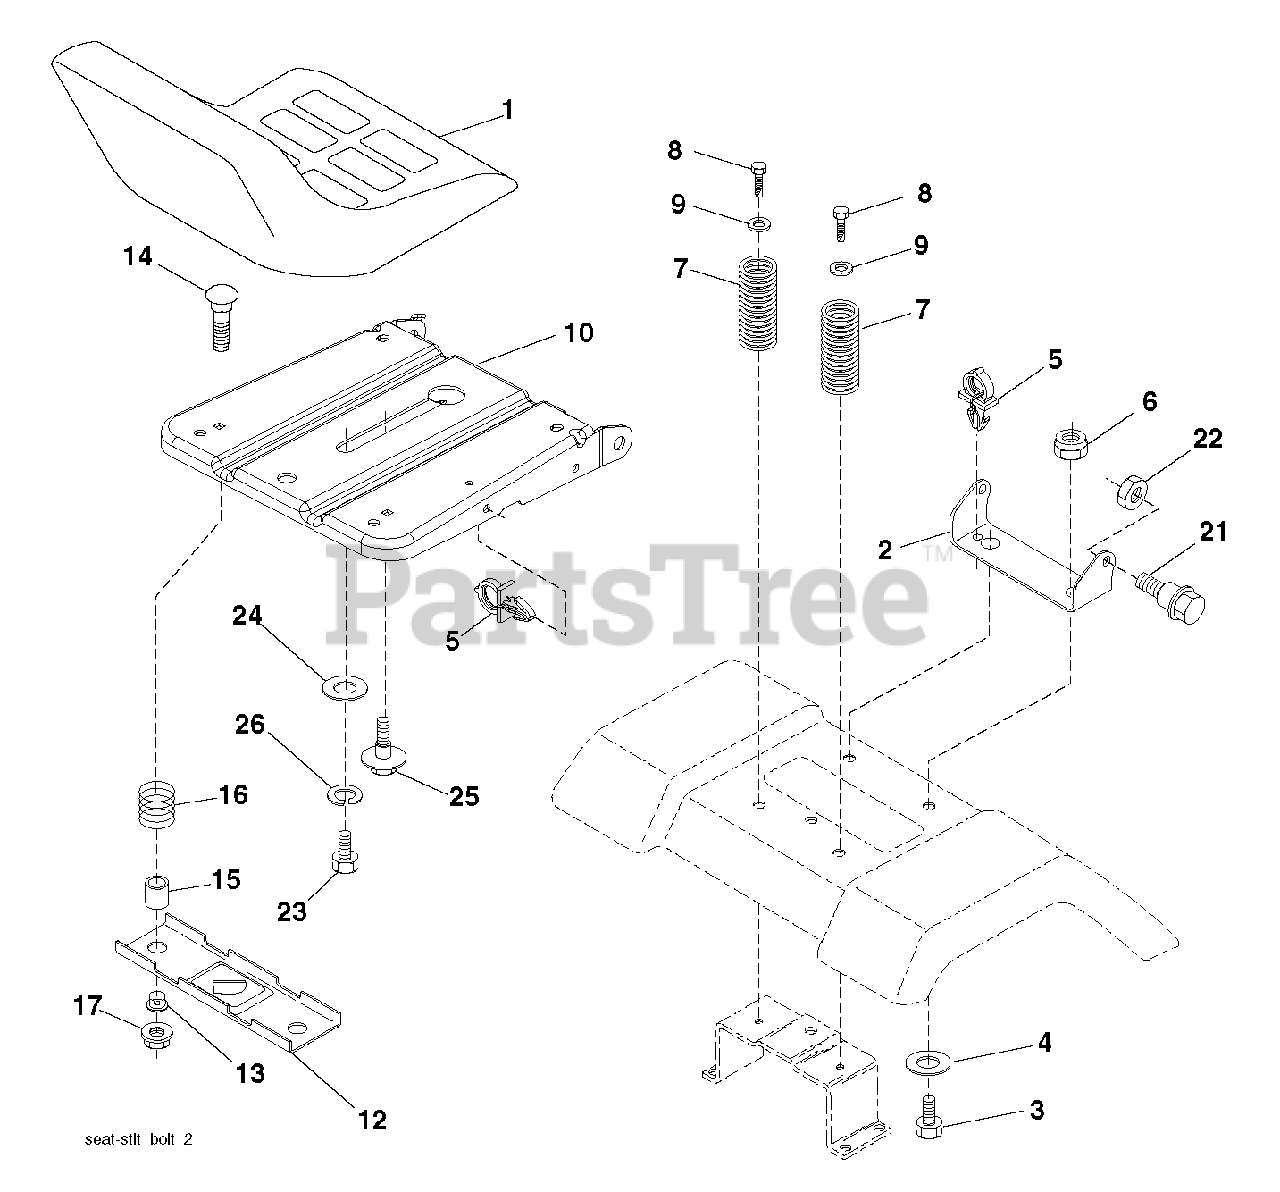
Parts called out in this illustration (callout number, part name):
1	SEAT.XG090.BLK.KB/BLT.NO-LOG
2	SEAT PIVOT BRKT
3	BOLT, HEX 3/8-16X1
4	WASHER PM
5	PUSH CLIP
6	NUT
7	SPRING COMPRESSION
8	SCREW 3/8-16X1
10	PAN.ASM.SEAT.1SLOT
12	BRKT.MNTNG.SWITCH.SEAT.BLACK
14	BOLT.ROUND.HEAD.SQUARE.NECK
15	SPACER SPLIT 28X.96
17	NUT T
21	BOLT.SHOULDER.5/16-18
22	NUT.71038.31-18.HEX.NYLOCK
23	BOLT.HEX.BLACK
25	BOLT,SHOULD
26	LOCKWASHER
